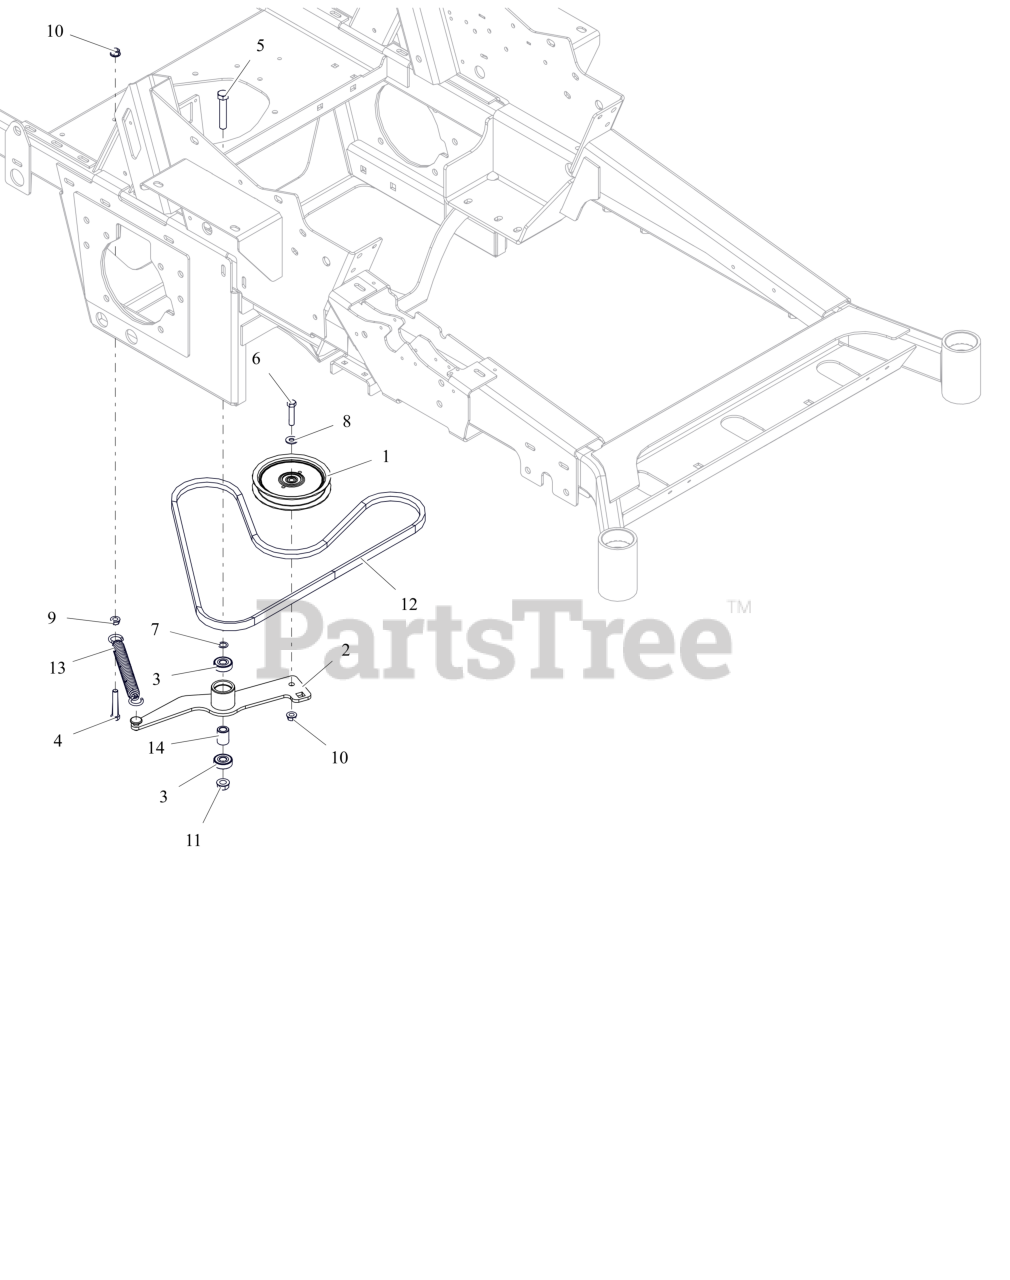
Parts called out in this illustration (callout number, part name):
1	IDLER, FLAT-5.00X.75
2	WLDMT, TRANSAXLE DRIVE IDLER ARM
3	BRG-BALL .500X1.38X.437
4	BLT,HEX .38-16X2.25 G5 ZCC
5	BLT,HEX .50-13X2.75 G5 ZCC
6	BLT, HEX .38-16X1.75 G5 ZCC
7	WASHER, .500X.750X.020 THRUST
8	WSHR,FLT .375X.875X.083 ZCC
9	NUT, SPNLK-FLG .38-16 G5 ZCC
10	NUT-LK-CTR-FLG .375-16 GF ZCC
11	NUT-LK-CTR-FLG .500-13 GG ZCC
12	V-BELT, HB SECTION
13	SPRING- EXTENSION
14	SPACER .510 X .867 X 1.1485
